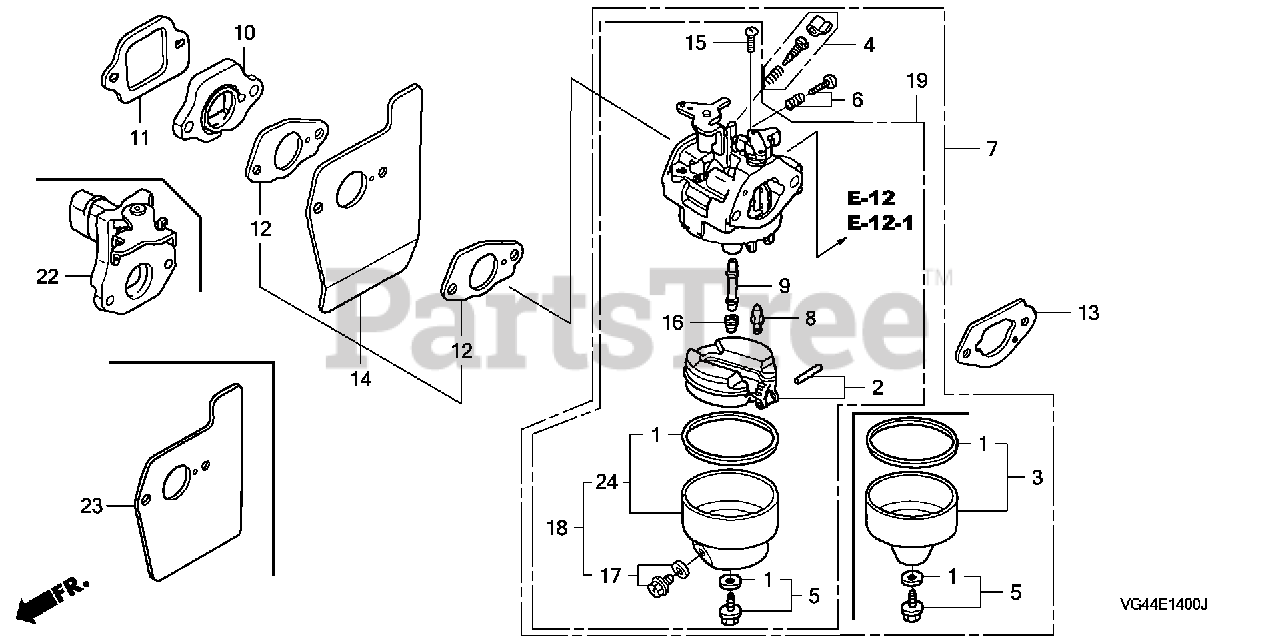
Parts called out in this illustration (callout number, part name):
1	GASKET SET
3	CHAMBER SET, FLOAT (CARBURETOR NO.)
5	SCREW SET
6	SCREW SET (THROTTLE STOP)
7	CARBURETOR ASSY. (BB62B C)
7	CARBURETOR ASSY. (BB62B D)
7	CARBURETOR ASSY. (BB62B E)
7	CARBURETOR ASSY. (BB62W C)
8	VALVE, FLOAT (CARBURETOR NO.)
9	NOZZLE, MAIN
10	INSULATOR, CARBURETOR
11	GASKET, INSULATOR
12	GASKET, CARBURETOR
13	GASKET, CARBURETOR
14	GUIDE, AIR
15	SCREW, PAN (5X6)
16	JET, MAIN (#60)
16	JET, MAIN (#62)
16	JET, MAIN (#65)
17	SCREW SET, DRAIN (CARBURETOR NO.)
18	CHAMBER SET, FLOAT (CARBURETOR NO.)
